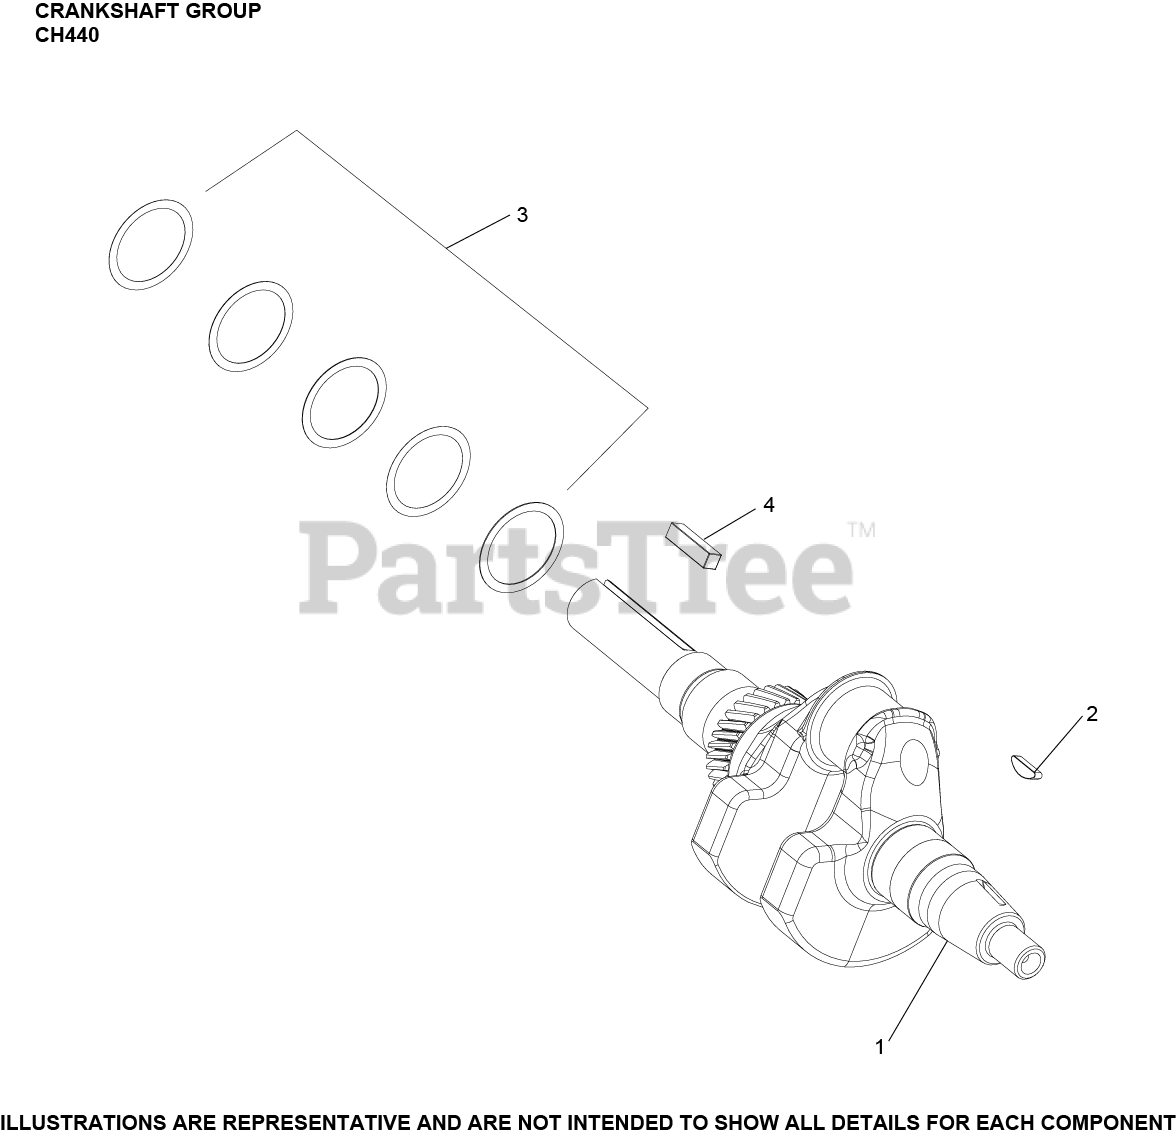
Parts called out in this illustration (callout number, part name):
1	CRANKSHAFT ASSEMBLY
2	KEY, FLYWHEEL
3	KIT, SHIM
